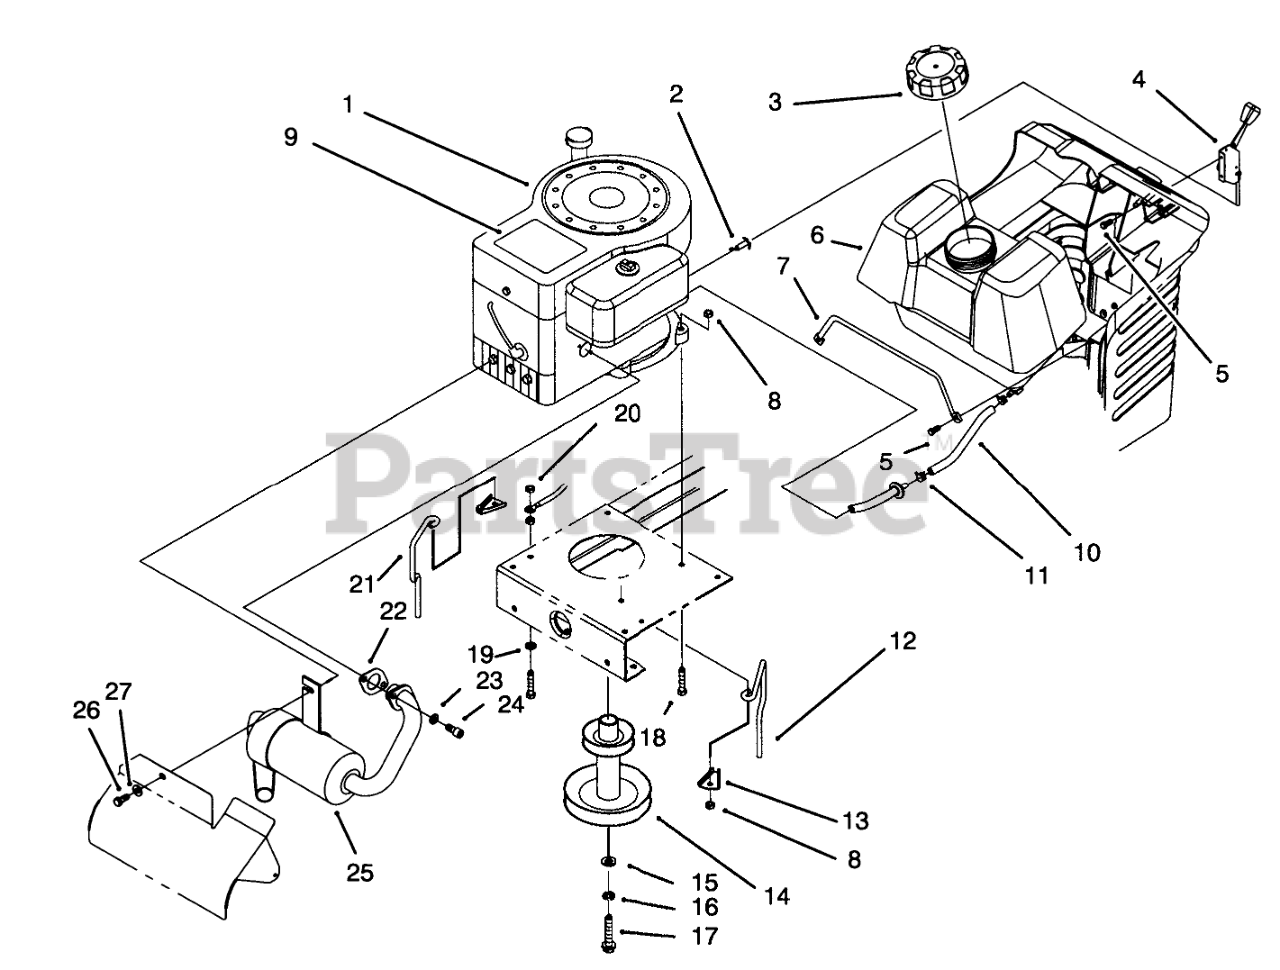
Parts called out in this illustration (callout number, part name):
1	Engine-13 H.P
2	THROTTLE CABLE ASM
3	GAS CAP ASM
4	THROTTLE CONTROL ASM
5	SCREW-SPECIAL
6	GAS TANK ASM
7	GAS TANK ROD
8	NUT-LOCK, NI
9	DECAL - ENGINE
10	HOSE-FUEL
11	CLAMP-HOSE
12	LH BELT GUIDE
13	ANCHOR-GUIDE, BELT
14	ENGINE PULLEY
15	WASHER-FLAT
16	WASHER-LOCK
17	SCREW-HH
18	SCREW-HH
19	WASHER-LOCK
20	NUT-KEPS
21	RH BELT GUIDE
22	GASKET-EXHAUST
23	WASHER-LOCK
24	SCREW-HSH
25	MUFFLER
26	SCREW-HH
27	WASHER-LOCK
